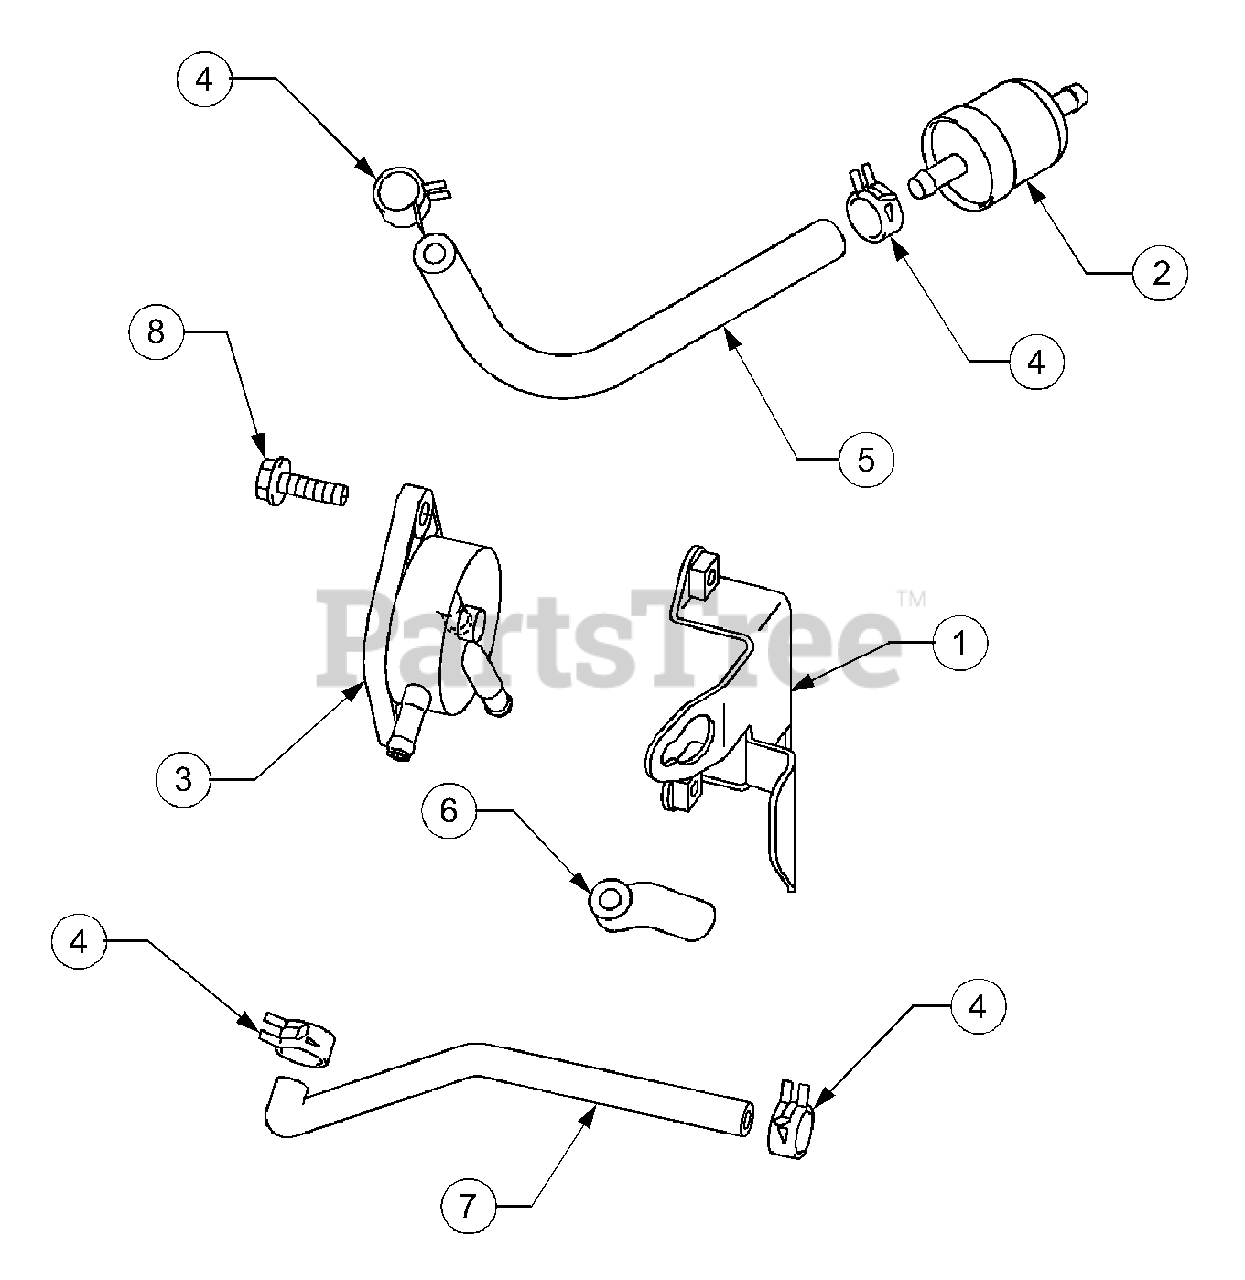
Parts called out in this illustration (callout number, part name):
1	Bracket, Comp
2	Filter, Fuel
3	Pump, Fuel
4	Clamp
5	Tube, 6.35x12.7x160
8	Bolt, Flanged
